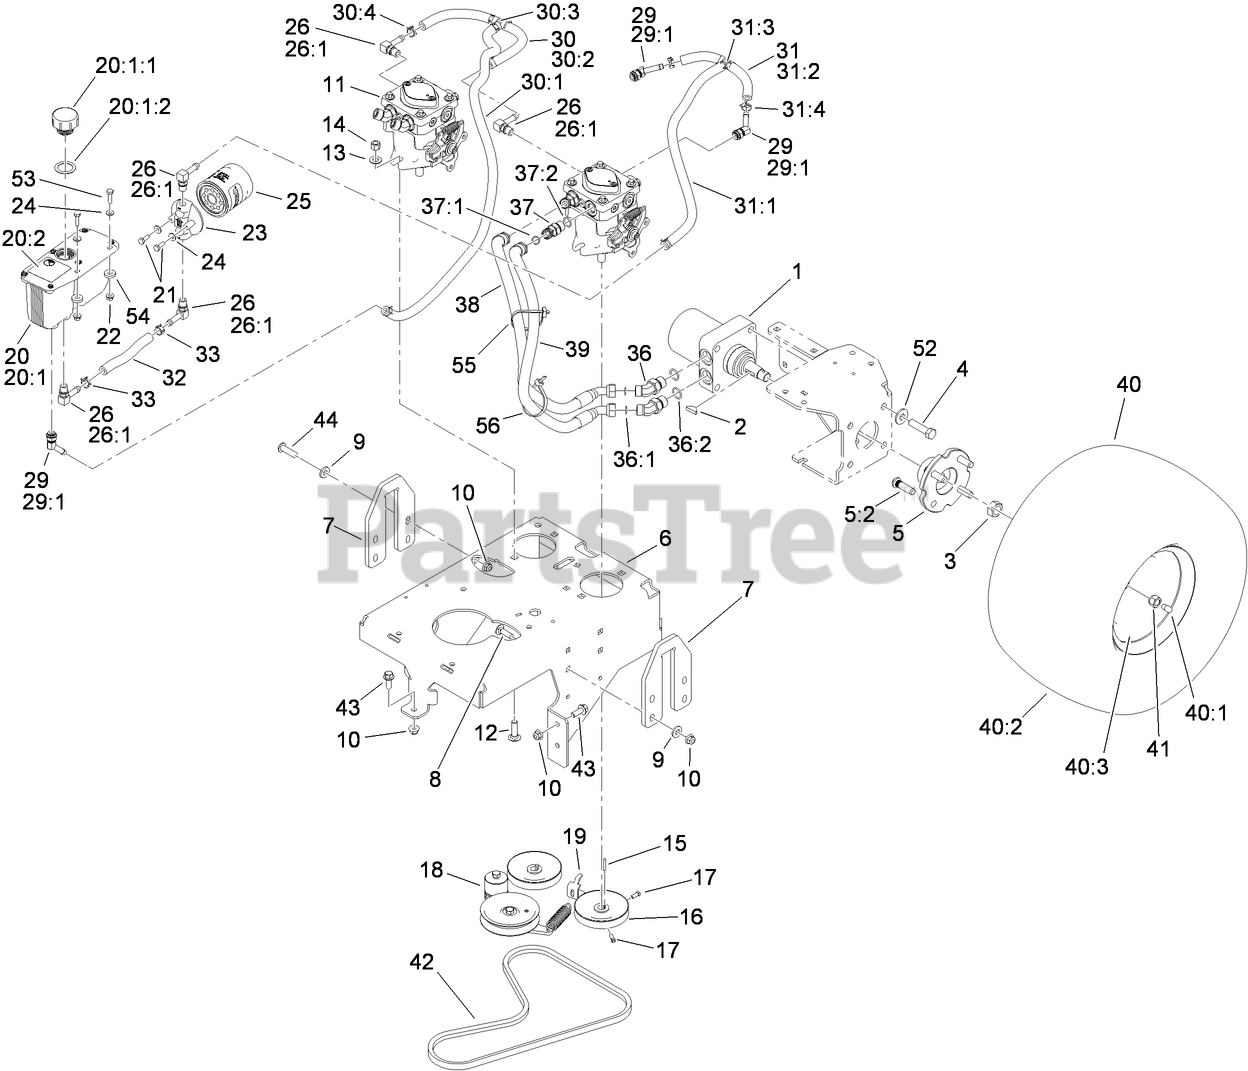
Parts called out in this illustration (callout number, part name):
1	HYD MOTOR ASM
2	KEY-WOODRUFF
3	NUT-MOTOR, WHEEL
4	SCREW-HH
5	WHEEL HUB ASM
5:2	STUD-TYPE, DRIVE
6	BASE-ENGINE
7	PLATE-LIFT
8	BOLT-CARR
9	WASHER-BELLEVILLE
10	NUT-HF, NI
11	HYD PUMP ASM
12	BOLT-CARR
13	WASHER-FLAT
14	NUT-LOCK, NI
16	PULLEY-PUMP
17	SCREW-SET
18	PUMP IDLER ASM
19	BRACKET-ANCHOR, SPRING
20	HYD RESERVOIR ASM
20:1	Reservoir-HYD
20:1:1	CAP-RESERVOIR, HYD
20:1:2	GASKET-CAP
20:2	DECAL-WARNING
21	SCREW-HH
22	NUT-HHF
23	HEAD-FILTER
24	WASHER-FLAT
25	ELEMENT-FILTER, 25 MICRON
26	FITTING-ELBOW, 90
26:1	O-RING
29	FITTING-BARBED, 45 DEG
29:1	O-RING
30	TANK HOSE ASM
30:1	HOSE-HYDRAULIC
30:2	HOSE-HYDRAULIC
30:3	FITTING-TEE, HOSE
30:4	Clamp-Hose
31	FILTER HOSE ASM
31:1	HOSE-HYDRAULIC
31:2	HOSE-HYDRAULIC
31:3	FITTING-TEE, HOSE
31:4	Clamp-Hose
32	HOSE-HYDRAULIC
33	Clamp-Hose
36	FITTING-HYD, 45 DEG
36:1	O-RING
36:2	O-RING
37	FITTING-HYD, 45 DEG
37:1	O-RING
37:2	O-RING
38	HYD HOSE ASM
39	HYD HOSE ASM
40	WHEEL ASM
40:1	STEM-VALVE
40:3	RIM-8 INCH
41	NUT-LUG
42	BELT-V, LOWER PTO
43	SCREW-HHF
44	SCREW-HSBH
52	WASHER-SPRING
53	SCREW-HH
54	SPACER
55	TIE-PLASTIC
56	TIE-CABLE
